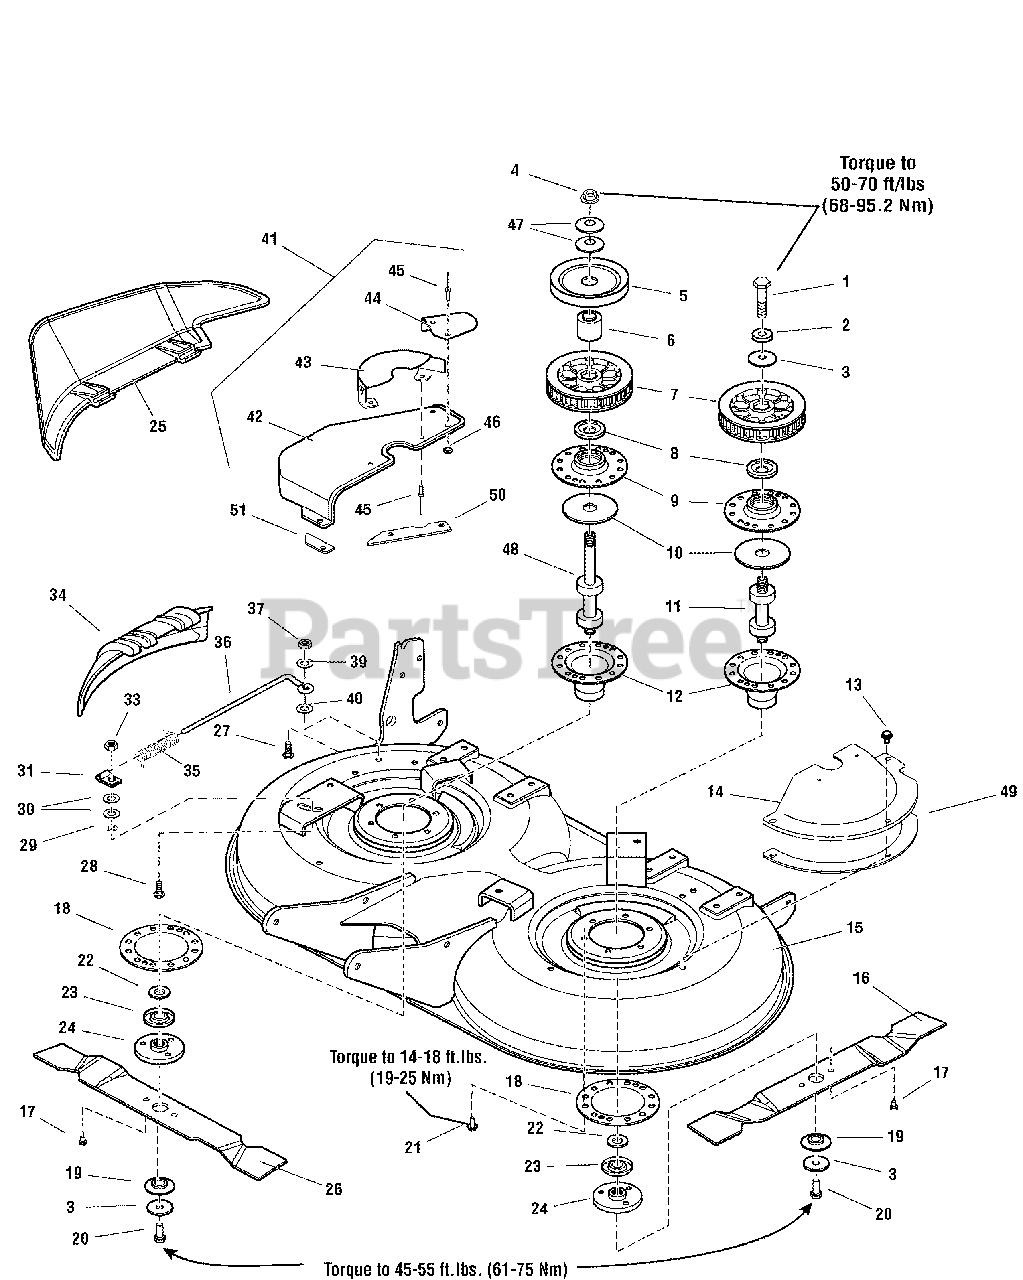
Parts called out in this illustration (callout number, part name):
1	CAPSCREW, Hex Head, 7/16-14 x 2-3/4 G8
2	WASHER, 7/16
3	WASHER, Spring
4	NUT, Hex Flange, 9/16-18
5	PULLEY
5	PULLEY, Drive
6	HUB
7	SPROCKET & FLANGE ASSEMBLY, w/Screws, 38 Tooth
8	SHIELD, Bearing Upper, Arbor
9	HOUSING, Arbor Top
10	GASKET, Foam Poly
11	ARBOR SHAFT & BEARINGS ASSEMBLY
12	HOUSING, Arbor Bottom with Lube Fitting
13	CAPSCREW, Taptite Hex Washer Head, 5/16-18 x 3/4
14	COVER, Arbor, LH
15	HOUSING ASSEMBLY, 40", Orange
15	HOUSING ASSEMBLY, 40", Red
16	BLADE, Mower, LH
17	PIN, Blade
18	ADAPTOR, Arbor
19	WASHER, Spline
20	CAPSCREW, Hex Head, 7/16-14 x 2-1/4 G8
21	CAPSCREW, Taptite Hex Washer Head, 5/16-18 x 1
22	WASHER, Shim
23	SHIELD, Arbor Bearing, Lower
24	ADAPTER, Blade
25	DEFLECTOR, Discharge
26	BLADE, Mower, RH
27	CARRIAGE BOLT, 5/16-18 x 1
28	CARRIAGE BOLT, 1/4-20 x 7/8
29	NUT, Push
30	WASHER, 1/4
31	CLAMP
33	NUT, Hex 1/4-20, ESNA
34	DOOR, Mulching, Black Plastic
35	SPRING, Torsion
36	ROD, Pivot
37	NUT, Hex 5/16-18, ESNA
39	WASHER, 5/16
40	NUT, Push
41	COVER ASSEMBLY, Arbor, RH (Includes Ref. Nos. 42 thru 46)
42	COVER, Arbor RH
43	GUARD ASSEMBLY, RH
44	GUARD, Extension
45	RIVIT, Pop
46	WASHER, 3/16 x 3/4 x 1/16
47	WASHER, Bellville
48	ARBOR SHAFT & BEARING ASSEMBLY
49	SHIM-Cover LH 7GA 40" Mower
50	SHIM-Cover RH 7GA 6.5 LG 40" Mower
51	SHIM-Cover RH 7GA 2.8 LG 40" Mower
